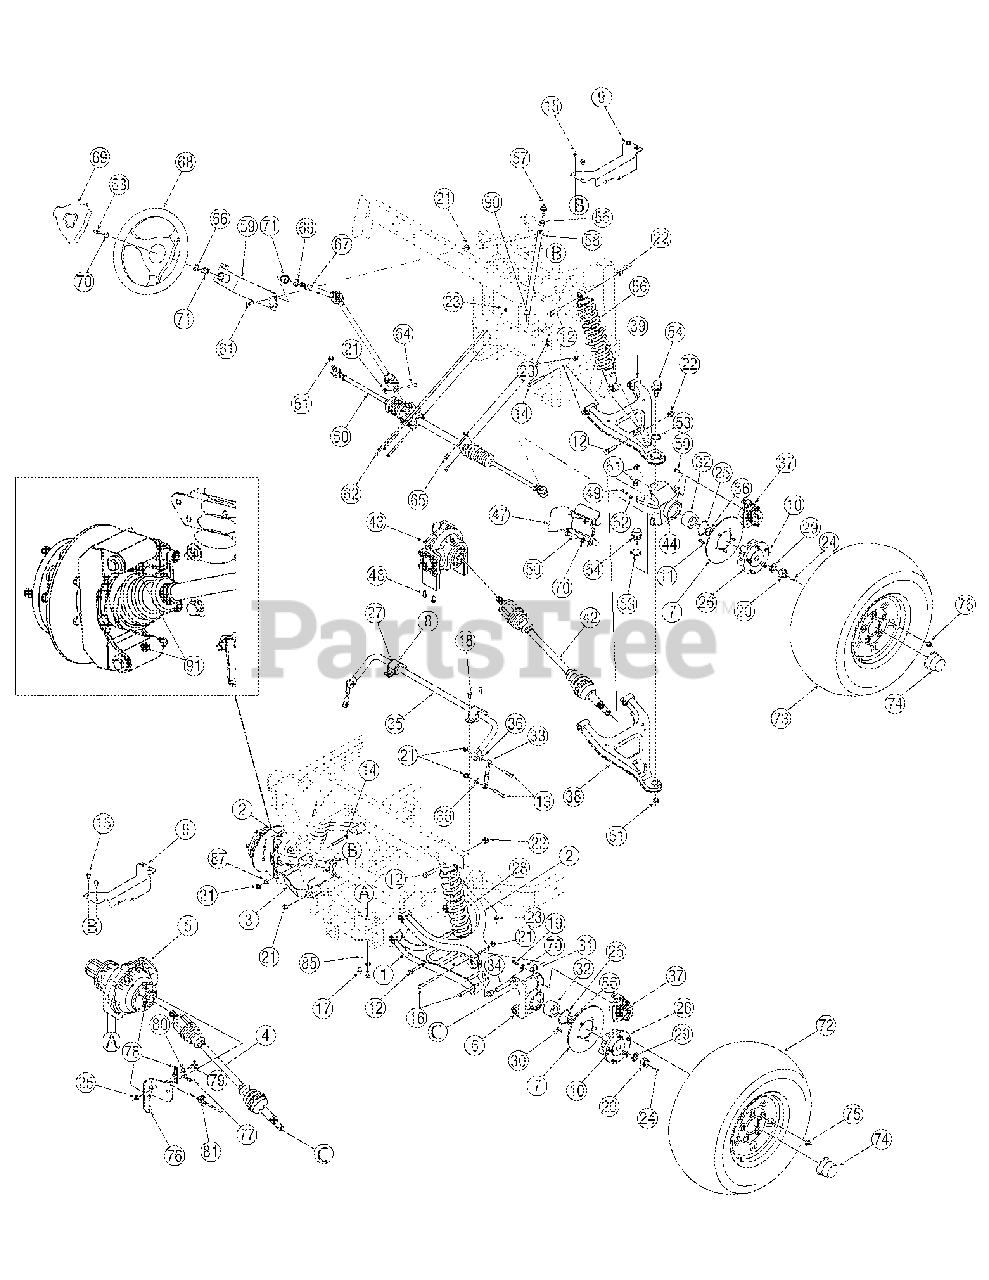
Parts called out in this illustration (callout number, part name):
1	Cont Assembly, lwr, r/rr
2	Cont Assembly, rr Upr
3	Cont Assembly, lwr, l/rr
4	Axle Assembly, cv Joint, 4X4
5	Diff Assembly, 4x4 Uv, Complete
6	Hsg, rr 4x4, mach
7	Disc, brake, 8.00x.188
10	Stud, rib Neck, 7/16-14 X 1.6
11	Screw, 1/4-20, .625, gr5, lock
12	Screw, 1/2-13, 2.00, gr5,
13	Screw, 3/8-16, 2.00, gr5,
14	Screw, 3/8-16, 3.00, gr8,
15	Scr, tt, 5/16-18, 0.500,
16	Screw, 3/8-16, 4.00, gr5,
17	Screw, 3/8-16, .75, gr5,
18	Screw, 5/16-24, .75, gr5,
19	Screw, m8-1.25, 25.00, std
20	Nut, slotted, 22x1.5
21	Nut, flglk, 3/8-16, grf, nylon
22	Nut, hexlk, 1/2-13, grb,
23	Nut, flglk, 5/16-18, grf,
24	Pin, cot, 5/32, 1.25
25	Ring, ret, dho-60
26	Hub, Wheel, 4x4
27	Bush, sway Bar
28	Shabs, 5.12 Stroke, rr, 4x4
29	Wash, flat, .88 X 1.38 X
30	Screw, hex. 1/4-20x.62 Gr8
31	Brg, flg, .625 X .750 X
32	Brg, dble Row, 60x30x37
33	Rod, cont, .375x3.886
34	Tube, pivot, rr/cont Arm
35	Bar, sway, rr, 4x4
36	Washer, Bell, .398 x 1.14 x .095
37	Brake, hyd, caliper, frt
38	Cont Assembly,r/frt,lwr
39	Arm Assembly,r/frt,upr
42	Axle Assembly,cv Joint,4x4
43	Diff Assembly,cfd,4x4
44	Hsg,knuckle,r/frt,mach
48	Screw,3/8-16,.75,gr5,std
49	Screw,1/4-20,1.00,gr5,spec
50	Screw,m8-1.25,25.0,gr8.8,std
51	Nut,nylock,m12x1.25
52	Nut,hex,1/4-20,gr5
53	Ring,ret,34x1.6
54	Ball joint, bj14d-6201
55	Clamp,hose,.490 Dia.
56	Shabs,5.12 Stroke,frt,4x4
57	Vent,3/8 Dia
58	Hose, fuel Line 5/16 inch ID
60	Steering Assembly, 4x4
61	Screw,3/8-16,1.00,gr5,std
62	Screw,5/16-18,3.50,gr5,std
63	Screw,5/16-18,.75,gr5,patch
64	Screw,3/8-16,1.25,gr5,std
65	Screw,5/16-18,.75,gr5,std
66	Ring,e Type,.750
68	Wheel,strg,soft Grip 3 Spoke
69	Cvr,Wheel,steering Soft Grip
70	Wash,bell,.340 X .872 X .
71	Brg,flg,.754id X 1.00odx.925
72	Wheel Assembly, RR/compl, 25x11-12
73	Wheel Assembly, RF/compl, 25x10-12
74	Cap, Wheel UV
75	Nut, lug, 7/16-14
77	Spr, ext, .38od x 2.10
78	Lever, Diff. Lock
79	Scr, shldr, .500 dia x .434
80	Brg, flg, nyliner, .500id x
81	Cbl, cont, diff, lock
82	Ftg, banjo ftg bolt, M10x1.
83	Ftg, banjo ftg crush
84	Screw, tt, 1/4-20x.500
85	Washer, Flat, .385 x .870
86	Wash, Flat, 1.250 x 1.938
87	Wash, Flat, .510 x 1.00
90	Clamp, Hose, Adj.
